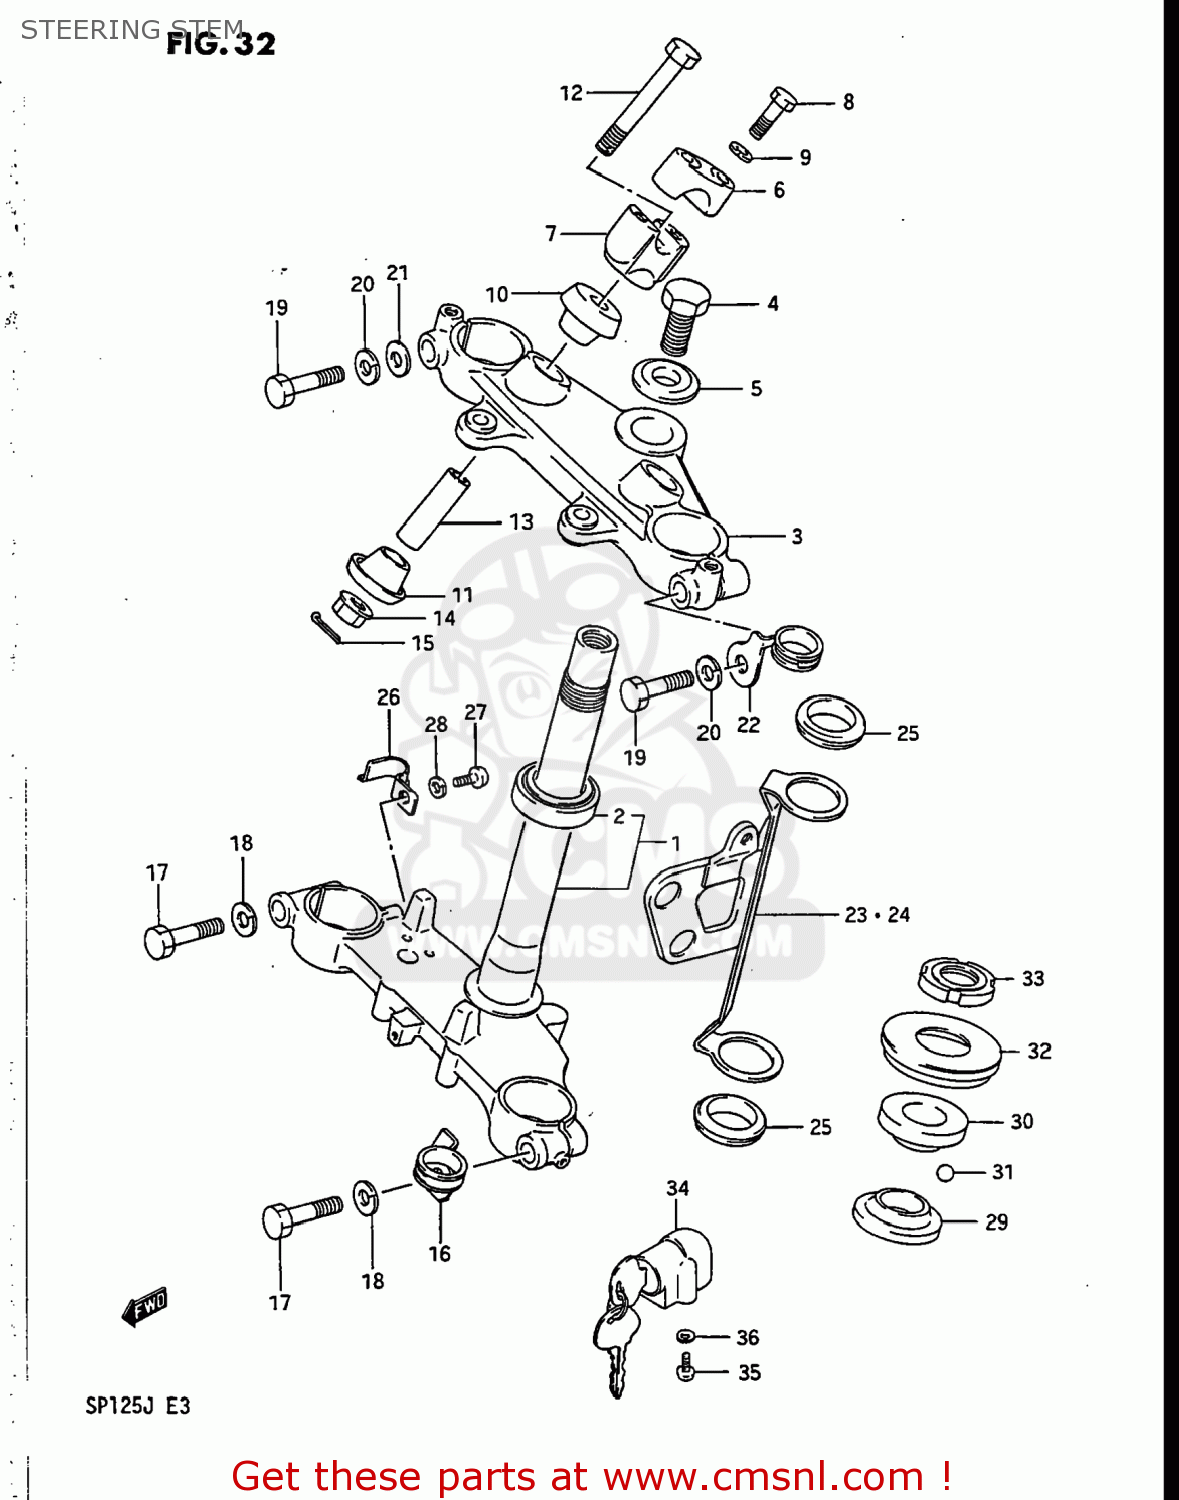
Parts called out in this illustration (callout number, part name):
1	STEM,STEERING
2	BEARING
3	HEAD,STEERING STEM
4	BOLT,STEERING STEM HEAD
5	WASHER
6	HOLDER,HANDLE UPR
7	HOLDER,HANDLEBAR LWR
8	BOLT
9	WASHER,LOCK,8.
10	RUBBER,HANDLE HOLDER
11	RUBBER,LWR
12	BOLT
13	SPACER
14	NUT
15	COTTER PIN
16	CLIP,LOWER
17	BOLT,INNER TUBE FITTING
18	WASHER,LOCK
19	BOLT,INNER TUBE FITTING
20	WASHER,LOCK
21	WASHER 10MM
22	CLIP,UPPER
23	BRACKET,HEADLAMP,R
24	BRACKET,HEADLAMP,L
25	CUSHION,HEADLAMP HSG BRACKET
26	CLIP
27	SCREW
28	WASHER,LOCK
29	RACE,STEERING INNER (SUJ)
30	RACE,STEERING,OUTER,UPPER
31	BALL
32	SEAL,STEERING UPR DUST
33	NUT,STEERING STEM
34	LOCK ASSY,STEERING
35	SCREW
36	LOCK WASHER
